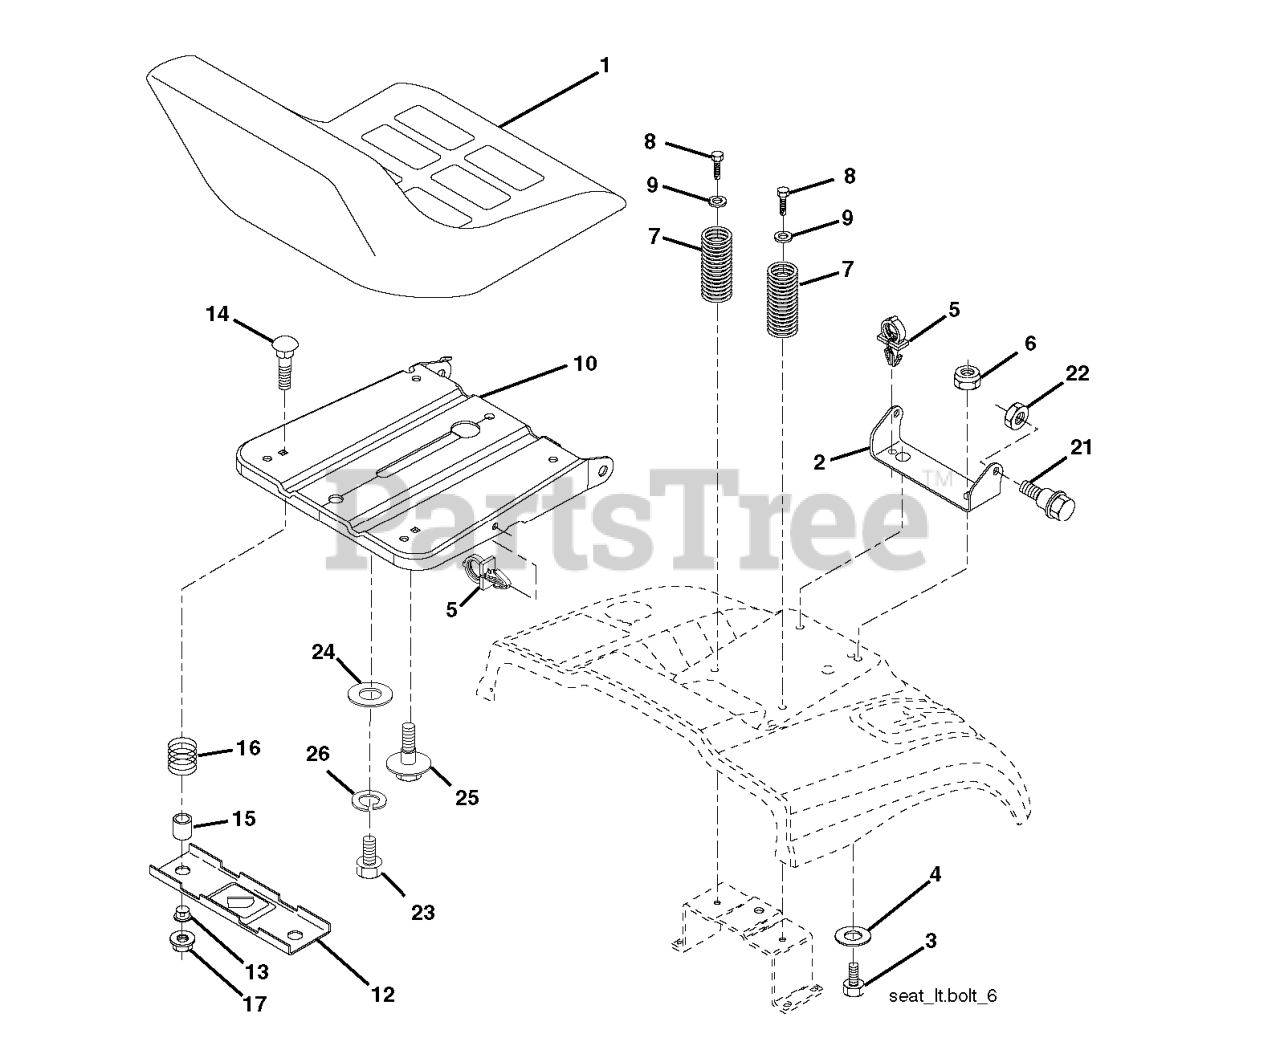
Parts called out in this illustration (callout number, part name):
1	SEAT.XG090.BLK.KB/BLT.NO-LOG
2	SEAT PIVOT BRKT
3	BOLT, HEX 3/8-16X1
6	NUT
7	SPRING COMPRESSION
8	SCREW 3/8-16X1
9	WASHER
10	PAN.ASM.SEAT.1SLOT
12	BRKT.MNTNG.SWITCH.SEAT.BLACK
14	BOLT.ROUND.HEAD.SQUARE.NECK
15	SPACER SPLIT 28X.96
17	NUT T
21	BOLT.SHOULDER.5/16-18
22	NUT.71038.31-18.HEX.NYLOCK
23	BOLT.HEX.BLACK
25	BOLT,SHOULD
26	LOCKWASHER
